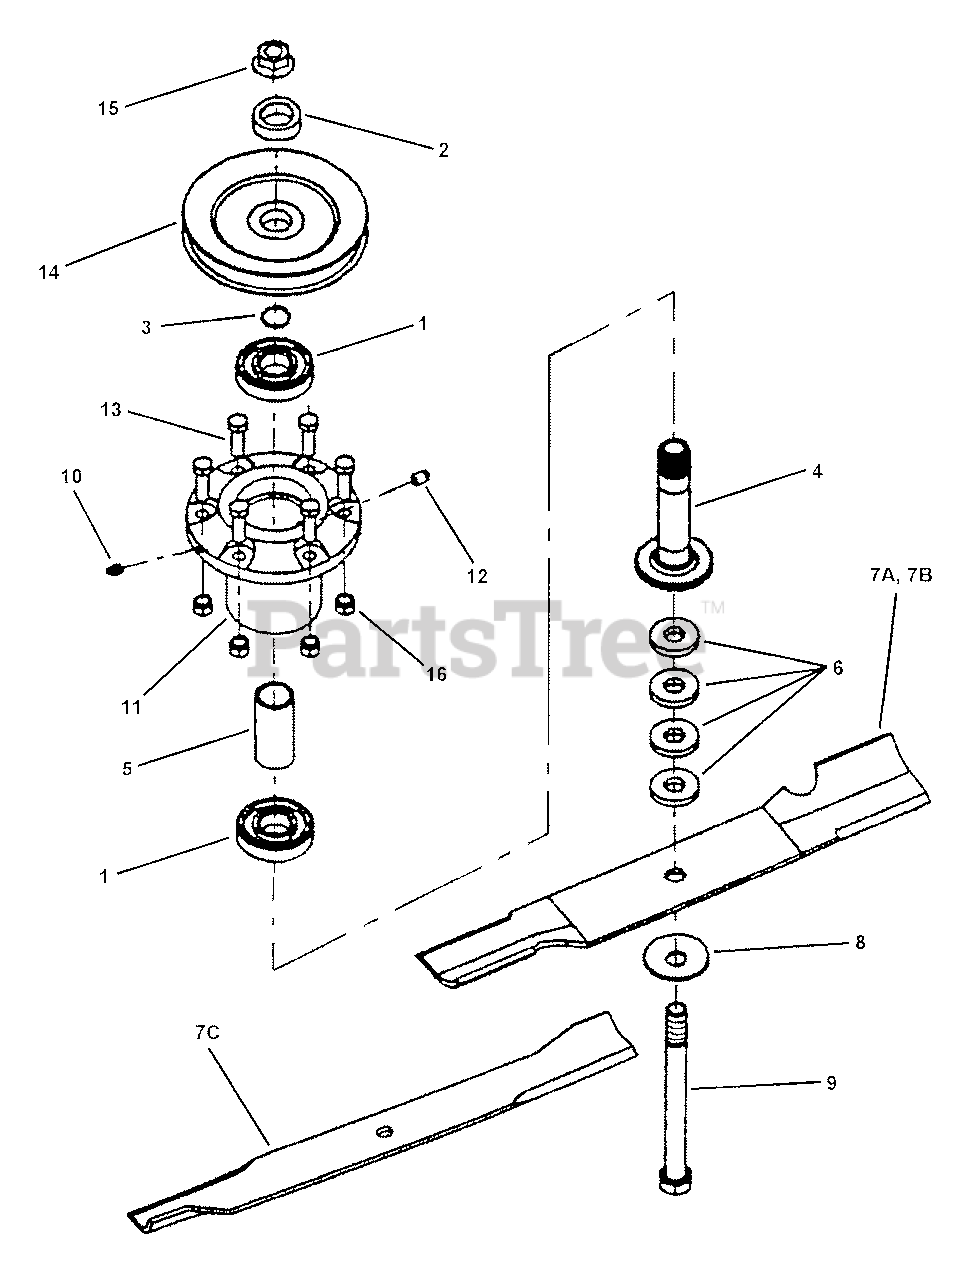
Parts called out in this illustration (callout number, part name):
1	BEARING, Sealed
2	WASHER, Spindle
3	SNAP-RING, Spindle Shaft
4	SHAFT, Spindle
5	SPACER, Bearing
6	SPACER, Blade
7A	BLADE, 21" (61" Deck) (High Lift)
7B	BLADE, 18" (52" Deck)
7C	BLADE, 21" (61" Deck) (Low Lift)
8	WASHER, Beveled
9	BOLT, 5/8-18 x 7-1/2" Hex Head Cap, Grade 5
10	LUBE FITTING, 1/4-28 Thread Forming
11	HOUSING, Cutter
12	VENT, Spindle
13	BOLT, 3/8-16 x 1-1/4" Rib Necked
14	PULLEY, 5-3/4" O.D. (61" Deck)
15	NUT, 5/8-18 Hex Flange Lock, Grade 5
16	NUT, 3/8-16 HEX NYLON LOCK
